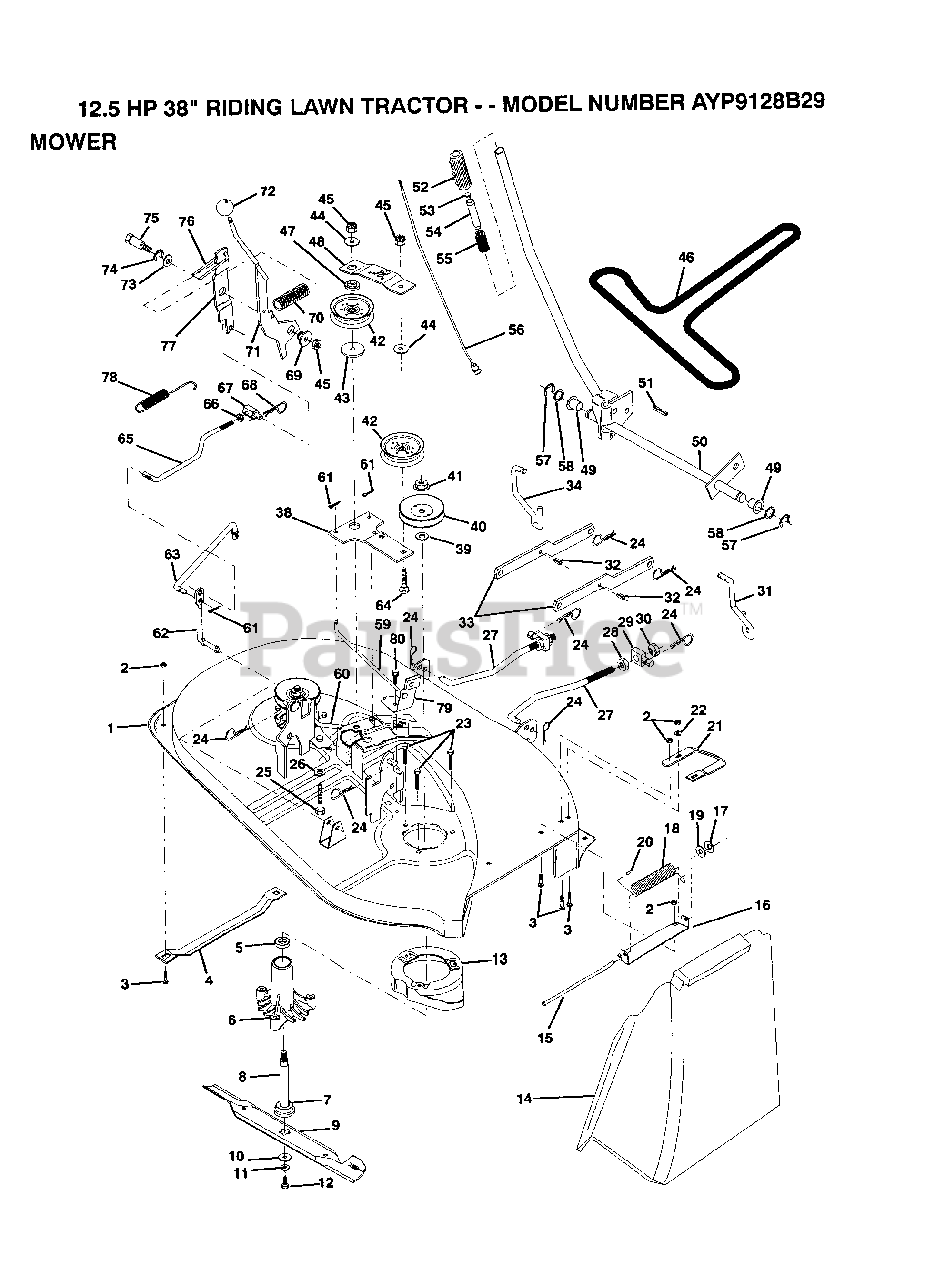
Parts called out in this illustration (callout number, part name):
3	BOLT
4	RUNNER-LH M
5	BEARING
6	HSG ASM MANDREL
7	BEARING.BALL
10	WASHER BLADE
12	BLADE BOLT
14	DEFLECTOR-SHLD T
15	ROD-HINGE T
17	NUT PUSH M
19	WASHER
20	CAP-SLEEVE LT
21	RUNNER RH
22	WASHER M
25	BOLT
26	WASHER GT
27	LINK.FRONT
28	NUT
29	TRUNION
30	NUT.LK.W/WSH.1/2.
31	LINK LIFT RH
32	SPRING PIN
33	SUSP ARM REAR
34	LIFT LINK LH
35	NUT
38	IDLER ARM ASSY
39	WASHER
42	FLAT IDLER PULLEY
43	SPACER RETAINER
44	WASHER GT
46	BELT-V.88.12.MW
47	RETAINER SPACER
48	IDLER ARM STIFF
49	NYLON BEARING
50	LIFT SHAFT ASM
51	PIN-GROOVE LT
52	GRIP
58	WASHER
59	BRAKE ROD RH
60	BRAKE ROD LH
62	PIVOT ROD
63	CLUTCH ROD SECOND
64	BOLT
66	NUT
67	TRUNION
68	RETAINER M
69	BUSHING
73	WASHER
74	RING
75	SHOULDER BOLT
76	SPRING KEEPER
77	CLUTCH ARM SECOND
78	RETURN SPRING
79	BRAKE ASM
80	SCREW
